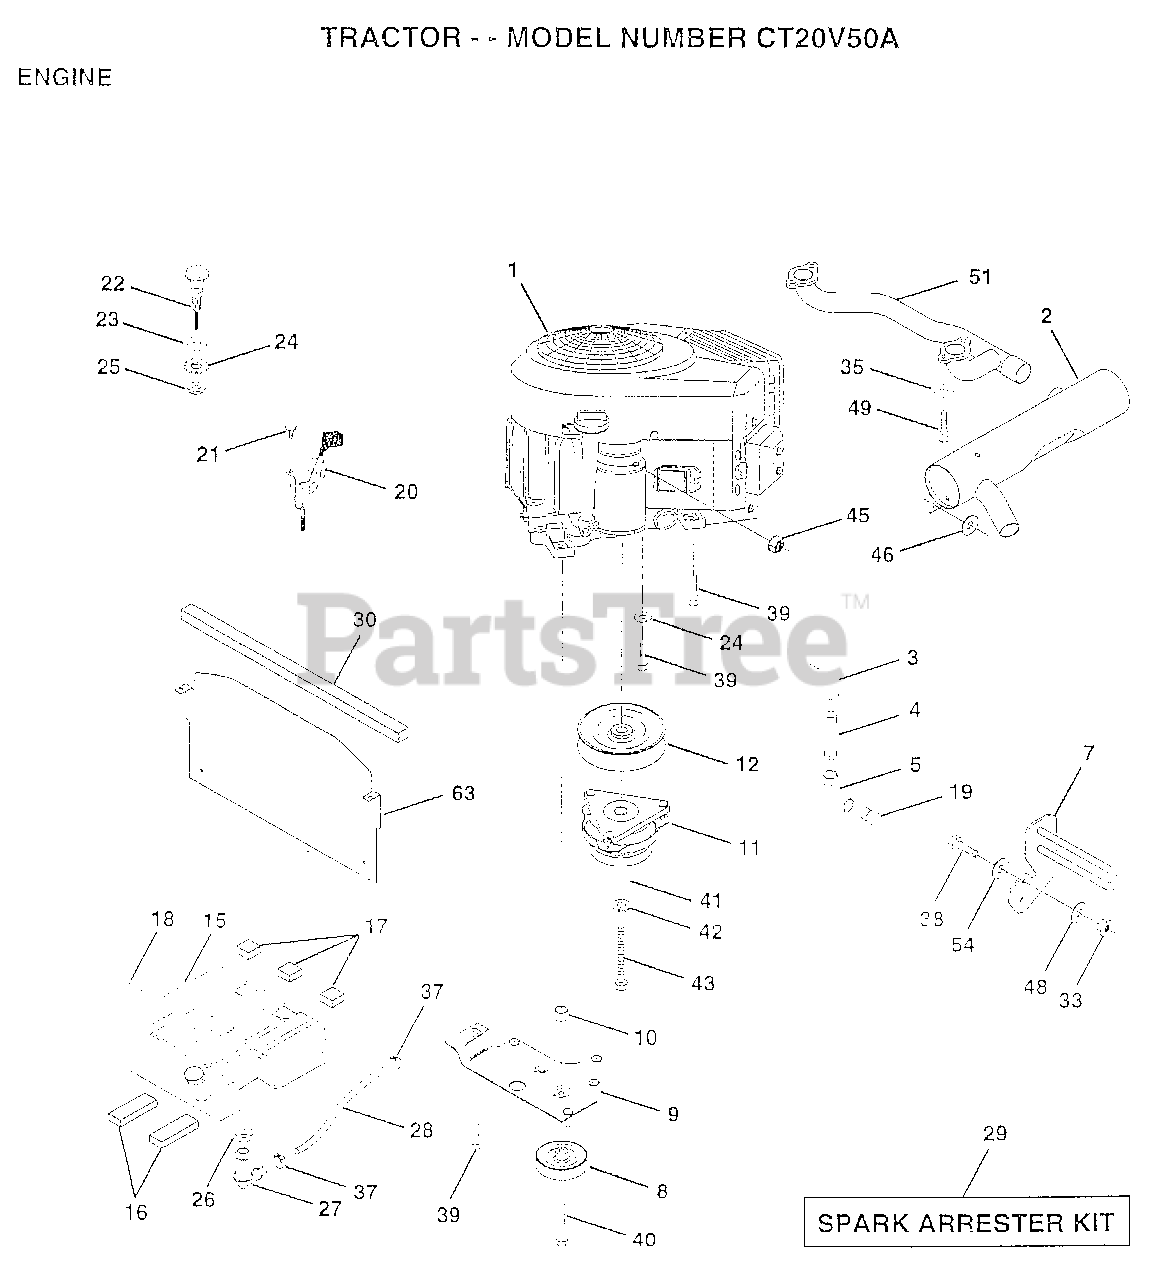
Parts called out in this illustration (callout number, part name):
3	STREET ELBOW LT
4	PIPE NIPPLE
5	ELBOW
10	BUSHING.
12	PULLEY.ENGINE.VGT
16	PAD IDLER TI
17	PAD-SPACER LT
18	CAP ASM FUEL
19	PLUG T
21	SCREW LT
23	WASHER
24	LOCKWASHER
26	BUSHING OUTLET T
27	STEM.TANK.FUEL
29	SPARK ARREST KIT
30	FOAM-STRIP LT
33	NUT
35	LOCKWASHER
37	HOSE CLAMP
38	"BOLT,HEX"
39	SCREW LT
40	SCREW.3/8-16X3.25
41	WASHER
42	LOCKWASHER
45	NUT
46	WASHER HYT
48	WASHER T
49	BOLT.HD.SOCKET.
51	PIPE.EXHAUST.B&S
54	WASHER
63	SHIELD.HEAT.VGT.
